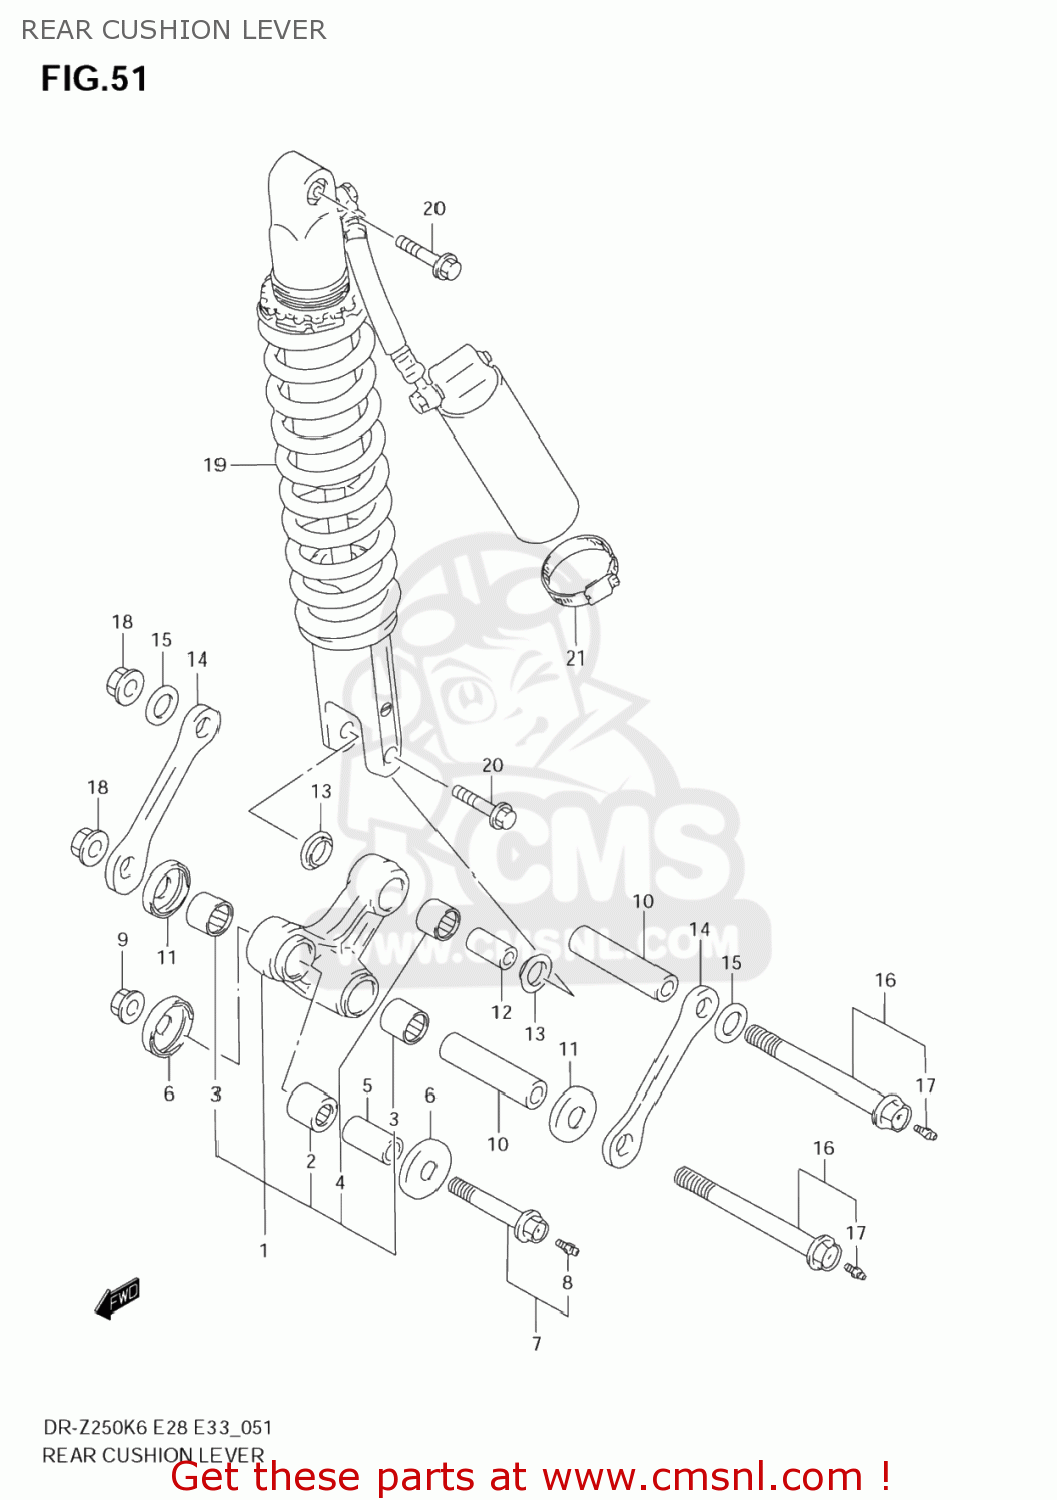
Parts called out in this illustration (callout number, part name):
1	LEVER SET,RR CUSHION
2	BEARING(20X27X30)
3	BEARING(20X27X23.5)
4	BEARING(17X24X20)
5	SPACER,RR CUSHION LEVER FR
6	SEAL,RR CUSHION LEVER FR DUST
7	BOLT,RR
8	GREASE NIPPLE
9	NUT
10	SPACER,RR CUSHION LEVER CTR
11	SEAL,RR CUSHION LEVER CTR DUST
12	SPACER,RR CUSHION LEVER
13	SEAL,RR CUSHION LEVER RR DUST
14	ROD,RR CUSHION LEVER
15	WASHER
16	BOLT,RR CUSHION LEVER CTR
17	GREASE NIPPLE
18	NUT
19	ABSORBER ASSY,RR SHOCK
20	BOLT,RR CUSHION ROD UPR
21	CLAMP
